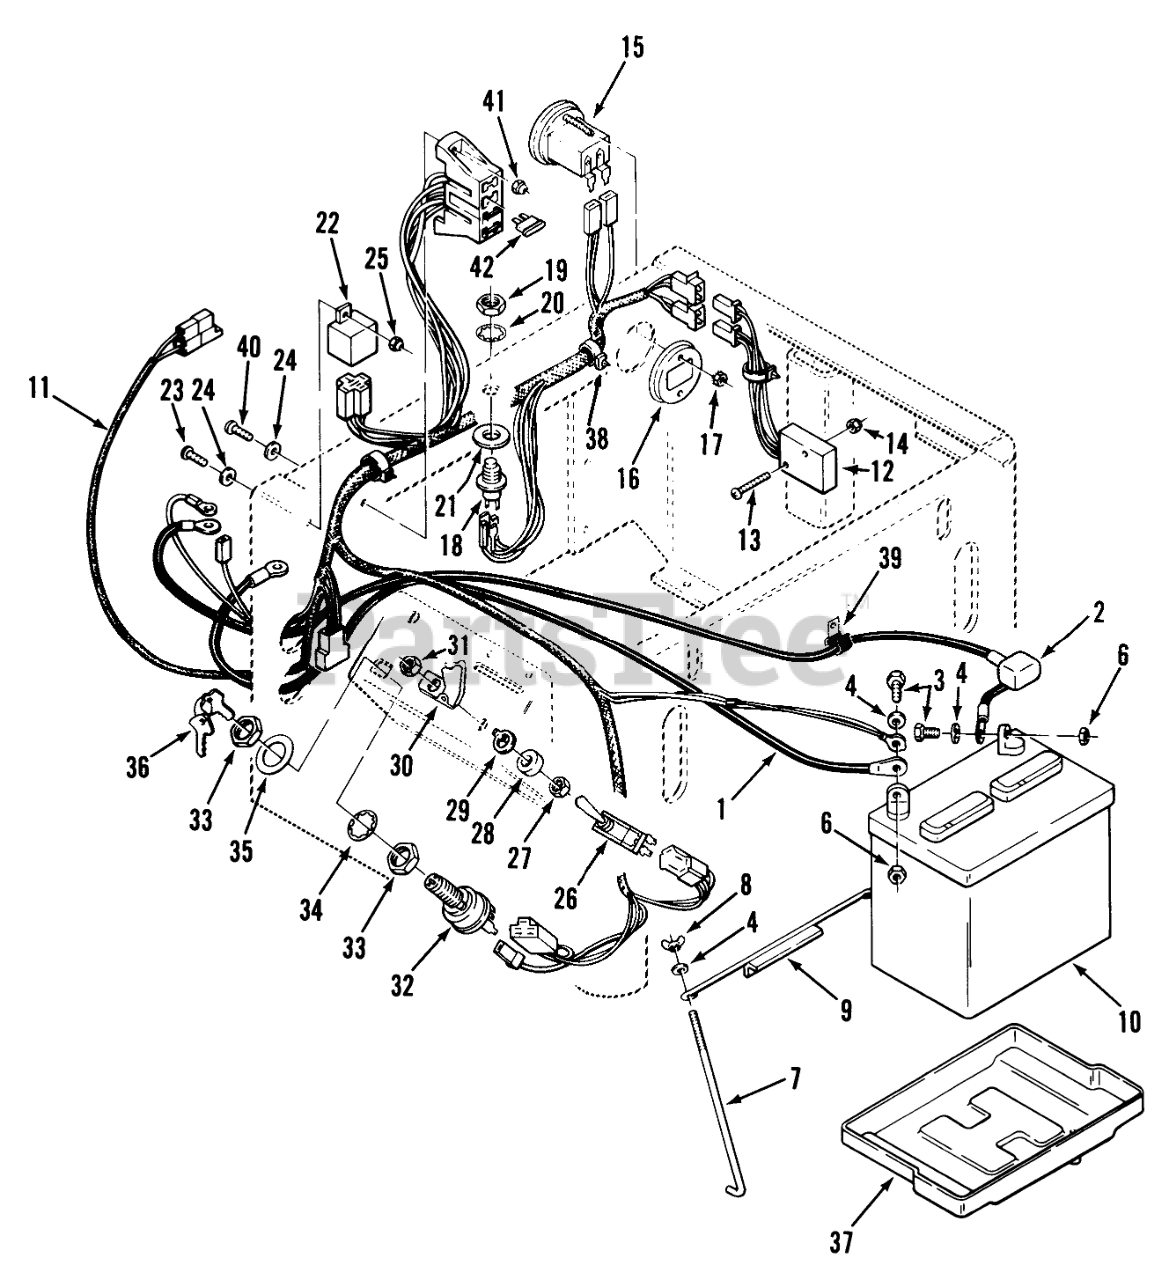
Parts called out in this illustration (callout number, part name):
1	WIRE ASM
2	Boot
3	Bolt
6	Nut
7	HOOK-BATTERY RETAIN
8	Nut
9	HOLDDOWN-BATTERY
10	Battery
11	MAIN-HARNESS & DIA
11	Wiring Harness 616-Z
12	SWITCH-ASS'Y NEUTRAL
13	Machine Screw
14	Nut
15	GAUGE-HOURMETER
17	Hex Nut
18	SWITCH-PLUNGER
19	HEX-NUT 5/8-24 F/W 116194
20	LOCKWASHER
21	WASHER
22	RELAY
24	WASHER
25	Nut
26	SWITCH-TOGGLE DPDT
27	NUT-HEX, SPECIAL
28	WASHER
29	TAB-WASHER
30	COVER-PTO SWITCH
32	SWITCH, KEY ASS'Y
33	HEX-NUT 13/16 UNEF
34	Washer-Lock
35	WASHER-SPECIAL
36	Keys (Set of 2)
37	TRAY-BATTERY
38	CLIP-SNAP IN
39	J-CLIP
41	Nut
42	FUSE-10 AMP
